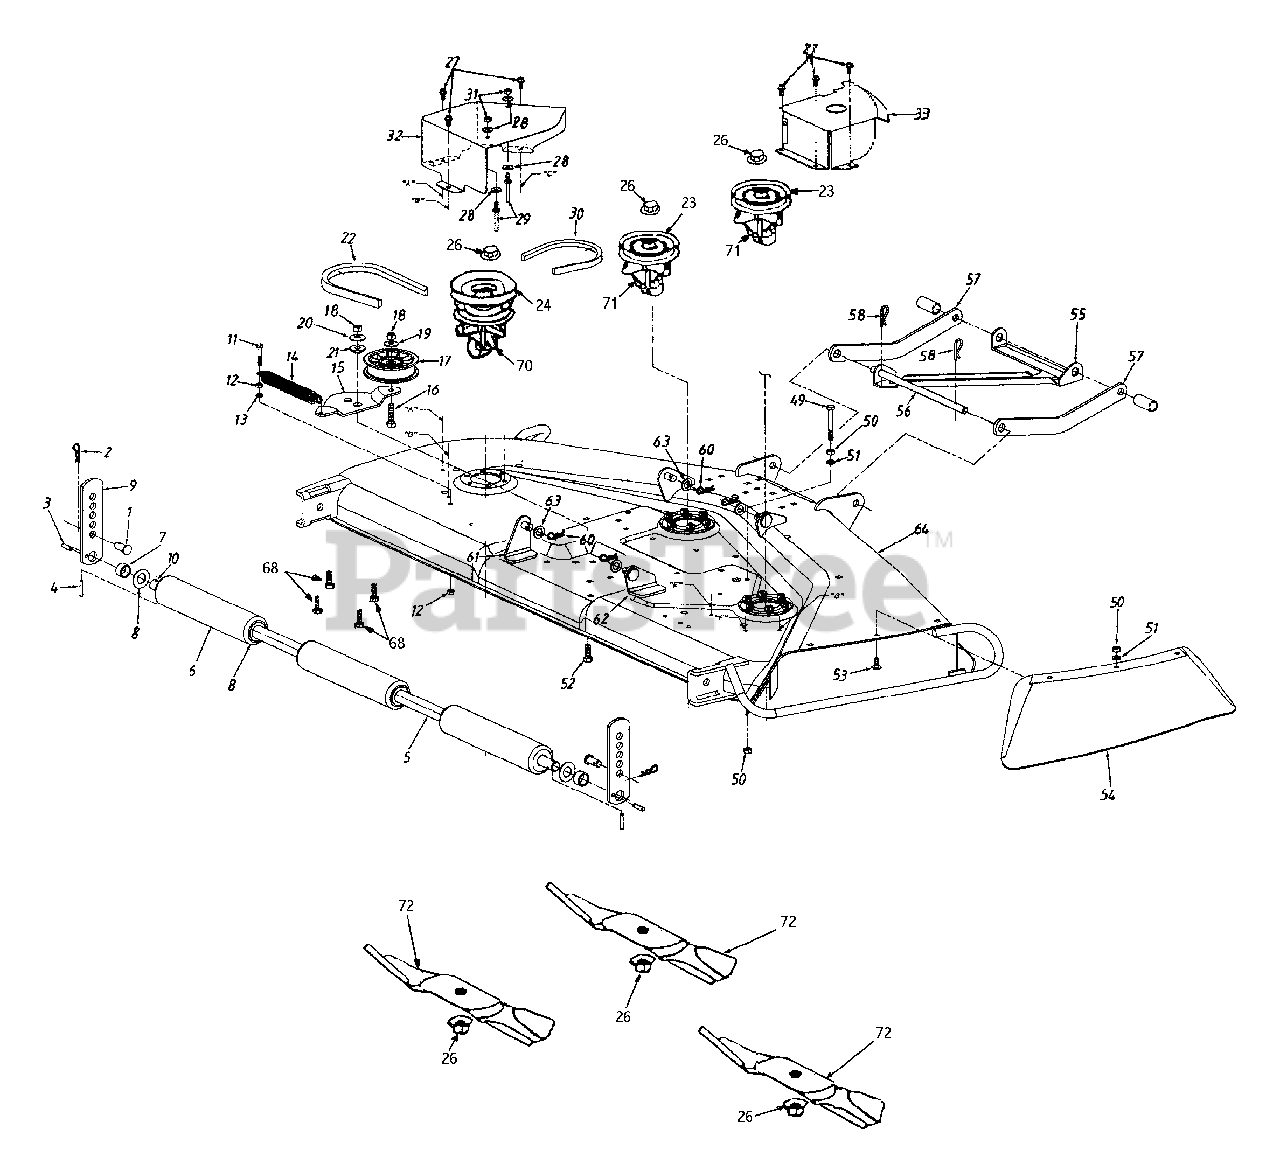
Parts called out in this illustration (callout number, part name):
2	Hairpin Clip
3	Spring Pin 1/4" x 1" Lg.
4	Spring Pin 3/16" x 1-1/4" Lg.
7	Spacer .75" I.D.
8	Fl-Wash. .76" I.D. x 1.5" O.D.
10	Roller Shaft
11	Hex Bolt 1/4-28 x 1.5" Lg. (Gr. 5)
12	Hex Nut 1/4-28 Thd.
13	L-Wash. 1/4" I.D.
14	Ext. Spring 7.33" Lg.
17	Idler Pulley
18	Hex Nut 3/8-24 Thd.
19	Bell-Wash. 3/8" I.D.
20	Bell-Wash. .39" I.D. x 1.13" O.D.
21	Shld. Spacer .625" I.D.
22	"V"-Belt
24	Double Deck Pulley
26	Hex Jam Nut 5/8-18 Thd.
27	Hex Wash. Hd. Scr. 1/4-20 x .5" Lg.
28	Bell-Wash. 1/4" I.D.
29	Belt Guard Pin
30	"V"-Belt
31	Hex Nut 1/4-20 Thd.
50	Hex Nut 5/16-18 Thd.
51	L-Wash. 5/16" I.D.
52	Hex Bolt 3/8-24 x 1" Lg.
53	Carr. Bolt 5/16-18 x .75" Lg.
60	Hairpin Clip
63	Fl-Wash. 1/2" I.D. x .93" O.D.
70	Spindle Ass'y. (L.H.)
71	Spindle Ass'y. (R.H. & Center)
72	Blade
